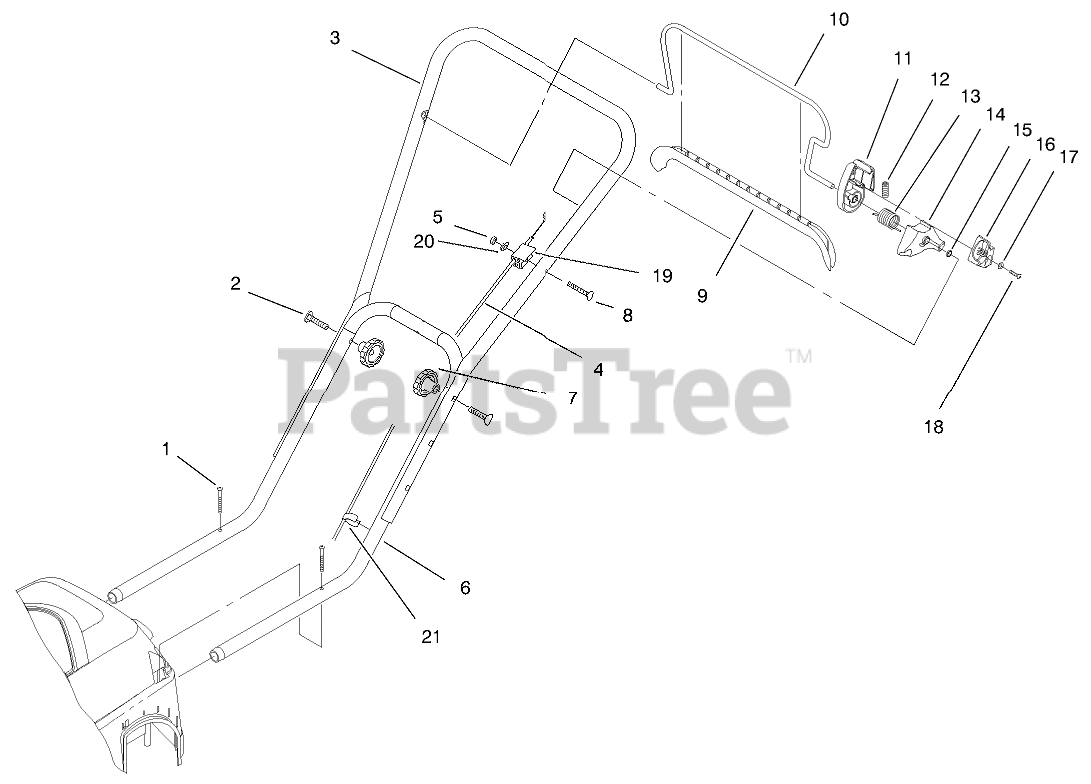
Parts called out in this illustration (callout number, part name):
1	SCREW-PPH
2	SCREW-HANDLE
3	Handle-Upper
4	CABLE - CONTROL
5	NUT-HEX
6	Handle-Lower
8	SCREW-HANDLE
9	COVER - BAIL
11	HOUSING - BAIL
12	SPRING - COMPRESSION
13	SPRING - BAIL
15	NUT - PUSH
16	SLIDE
17	WASHER - FLAT
18	SCREW-PPH
19	SUPPORT - CABLE
20	WASHER-FLAT
21	CLIP - CABLE
